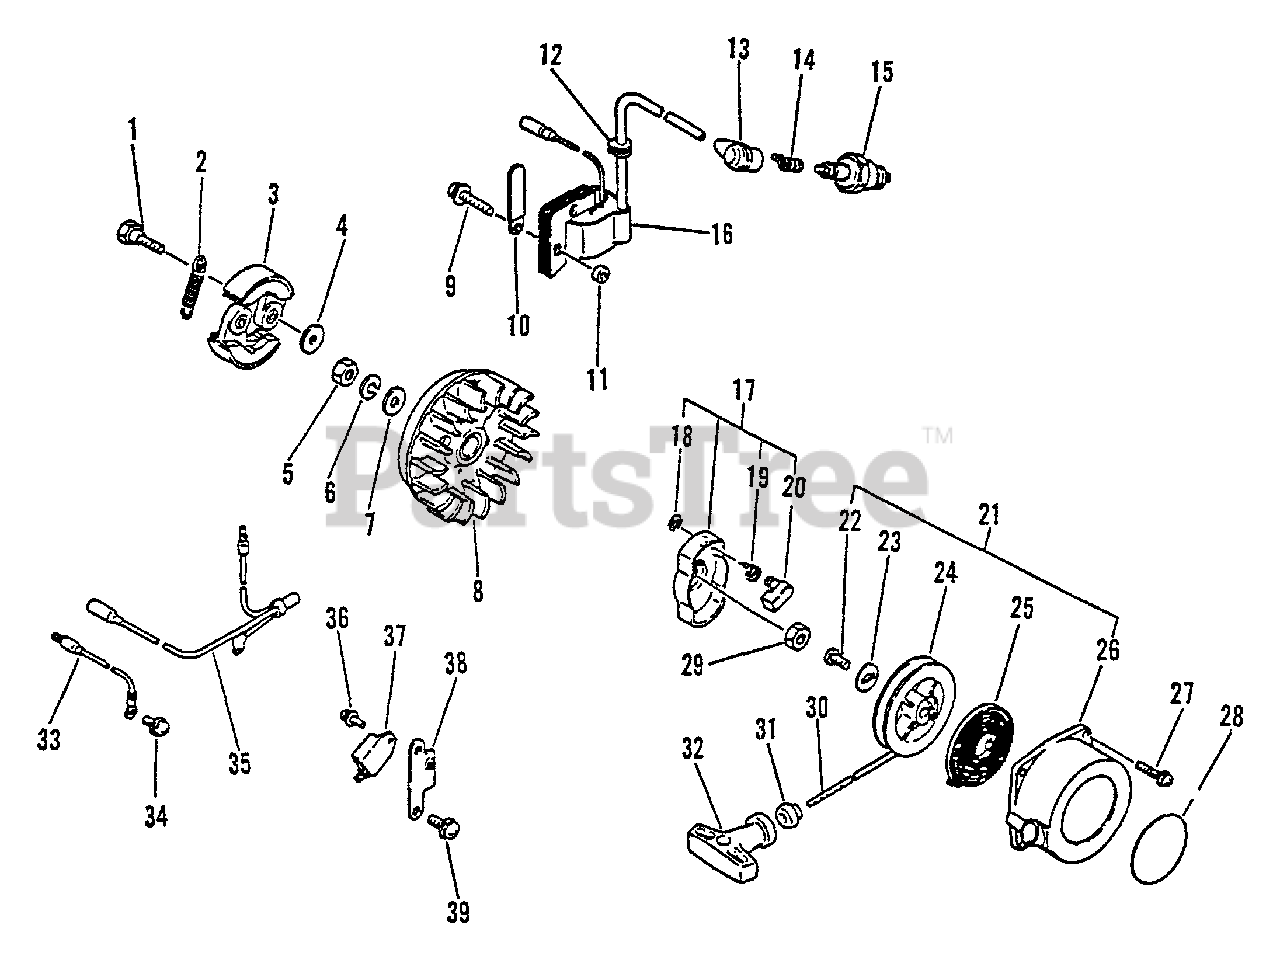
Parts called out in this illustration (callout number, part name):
1	BOLT, CLUTCH
2	SPRING, CLUTCH
3	SHOE, CLUTCH
4	WASHER - 6
6	LOCKWASHER - 8
8	FLYWHEEL
9	SCREW - 5X25
13	CAP, SPARK PLUG
14	TERMINAL, SPARK PLUG CAP
15	SPARK PLUG -- BPM-7A
16	COIL, IGNITION
17	STARTER PAWL ASSY
18	RING, RETAINING - 4
19	SPRING, RETURN
20	PAWL, STARTER
21	STARTER ASSY
24	REEL, ROPE
25	SPRING, REWIND
26	CASE, STARTER - ORANGE
27	SCREW - 4X20
28	LABEL - ECHO
30	ROPE, STARTER - 4X880
31	GUIDE, ROPE
32	GRIP, STARTER
33	LEAD - GROUND
34	SCREW - 5X10
36	SCREW - 4X8
37	COIL, IGNITION
38	BRACKET, IGNITION COIL
39	SCREW - 5X12
